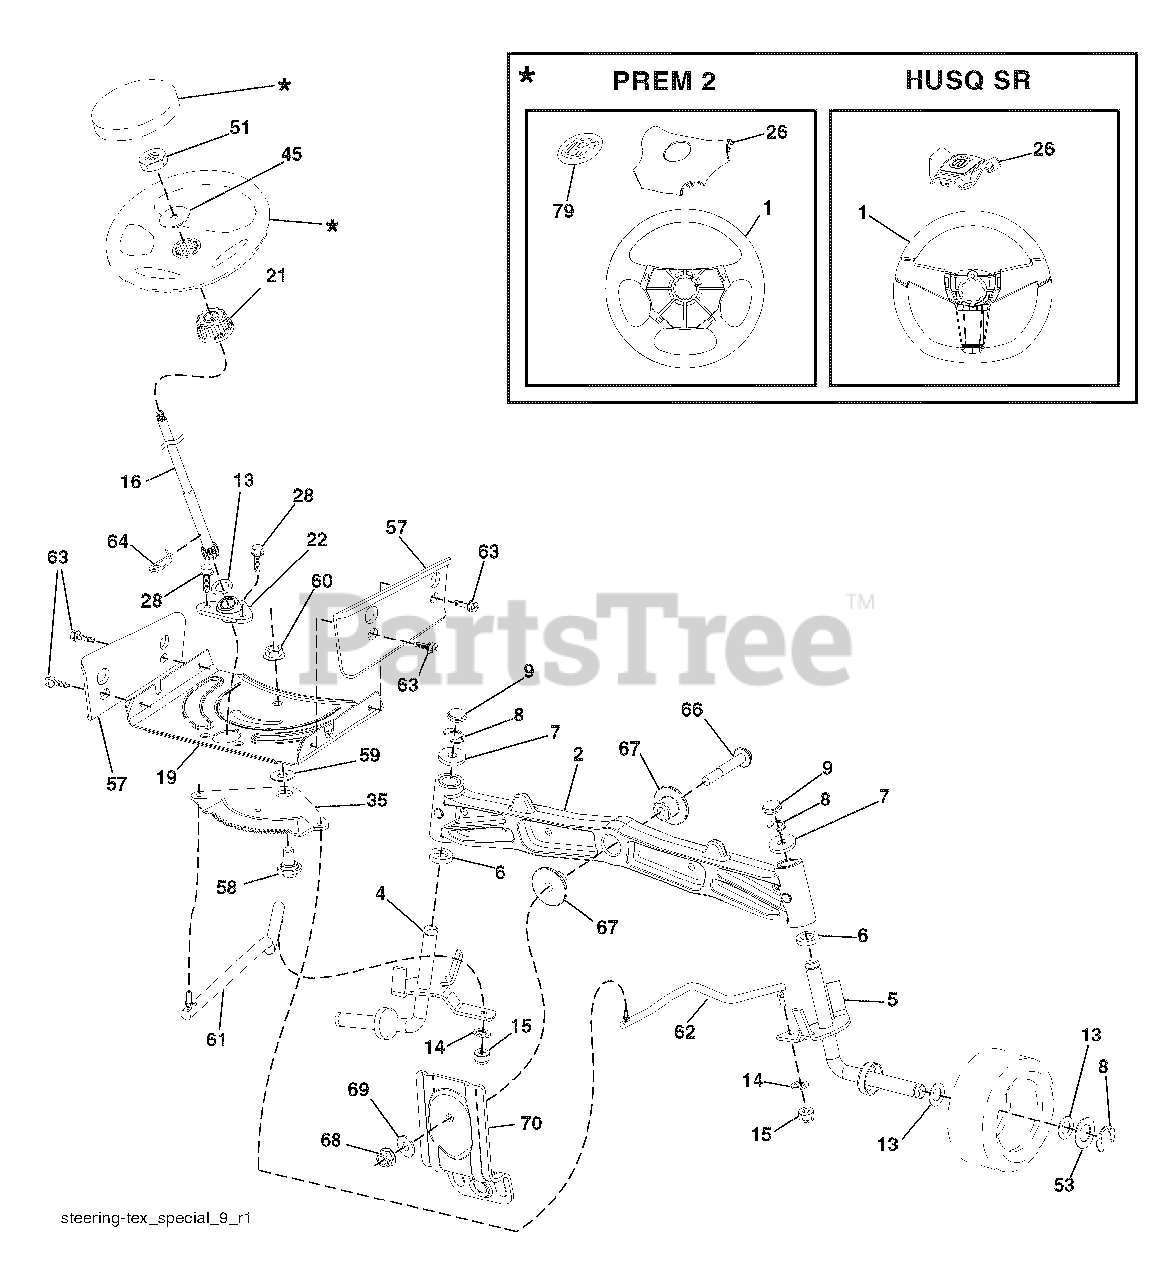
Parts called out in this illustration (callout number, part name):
1	Wheel, Steering
2	Axle Asm., Front
4	Spindle Asm., LH
5	Spindle Asm., RH
6	Bearing, Race Thrust Harden
7	Washer 25/32 x 1-5/8 x 16 Ga.
8	Ring, Clip #T5304-75
9	Cap, Spindle
13	Washer 25/32 x 1-1/4 x 16 Ga.
14	Washer, Lock Hvy Hlcl Spr 3/8
15	Nut, Crown Lock 3/8-24 unf
16	Shaft Steering
19	Plate Steering
21	Adapter, Wheel Steering
22	Bushing, Strg. Blk
26	Insert, Wheel Steering
28	Screw 3/8-16 x 3/4
35	Gear, Sector Plate
45	Washer 9/16 ID x 2-3/8 OD 12 Ga.
51	Nut Hex Jam Toplock 1/2-20 unf
53	Washer Hardened .793 x 1.637 x .060
57	Bracket Upstop
58	Bolt Shoulder Sector Pivot CFM
59	Washer Thrust Sector Steering
60	Nut Flange Lock 5/8-11
61	Draglink LH
62	Draglink, RH
63	Screw 5/16-18 x 3/4
64	Retainer Clip Spring Steering
66	Bolt Hex Fghd 7/16-14 x 3 Serr
67	Bushing PM Front Axle
68	Nut Lock Flange 7/16-14 Gr. 5
69	Washer 1.5 x .505 x .118
70	Bracket Deck Susp. Front
